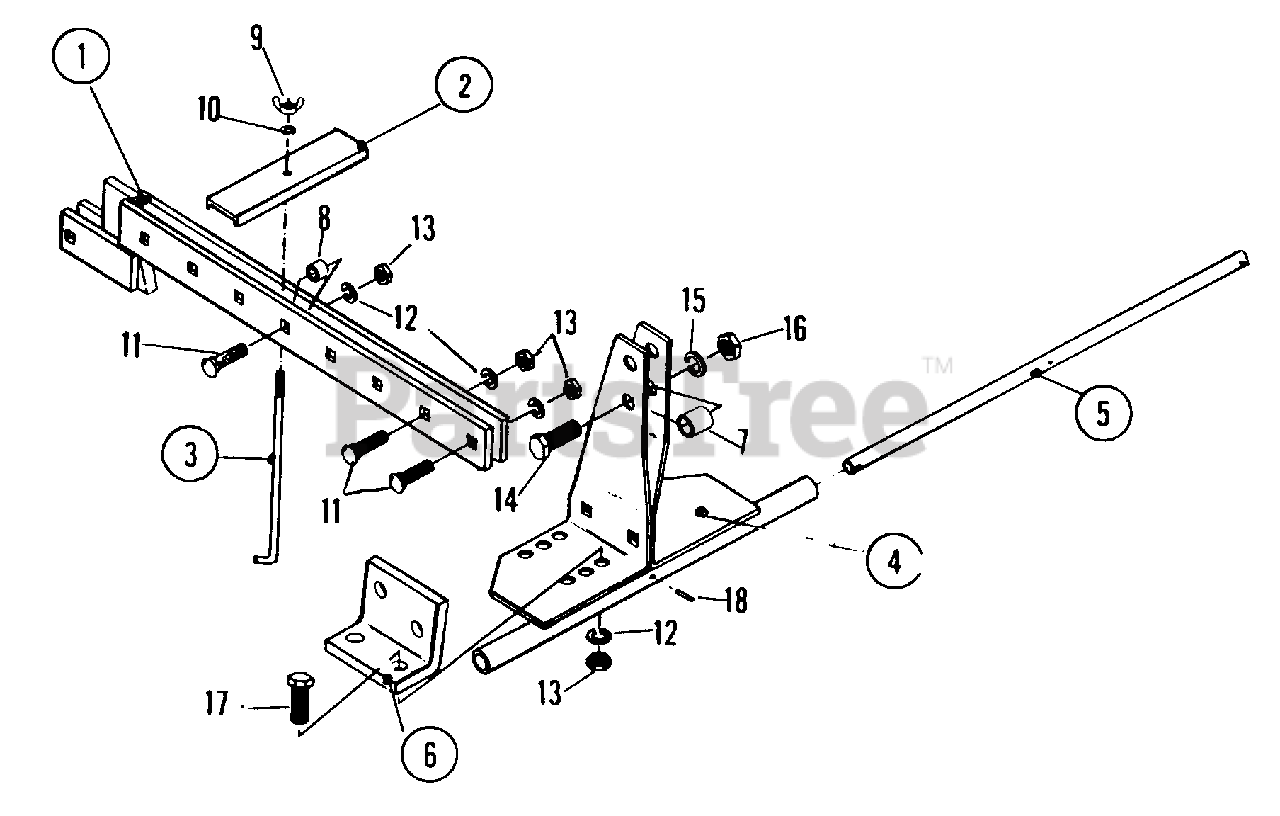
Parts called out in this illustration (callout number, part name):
1	DRAWBAR
2	STRAP, WEIGHT
3	ROD, WEIGHT STRAP
4	ADAPTER
5	ROD, LOWER LINK
6	PLATE, MOUNT
7	SPACER, UPPER LINK
8	BUSHING
9	WING-NUT, 3/8
10	LOCKWASHER, 3/8"
11	BOLT, 1/2 x 2" CARRIAGE
12	LOCKWASHER, 1/2"
13	NUT, 1/2 HEX
14	BOLT, 5/8 x 2-3/4 HEX
15	LOCKWASHER, 5/8
16	NUT, 5/8 HEX
17	BOLT, 5/8 x 1-1/2 HEX
18	SPIROL-PIN, 3/16D x 1"
